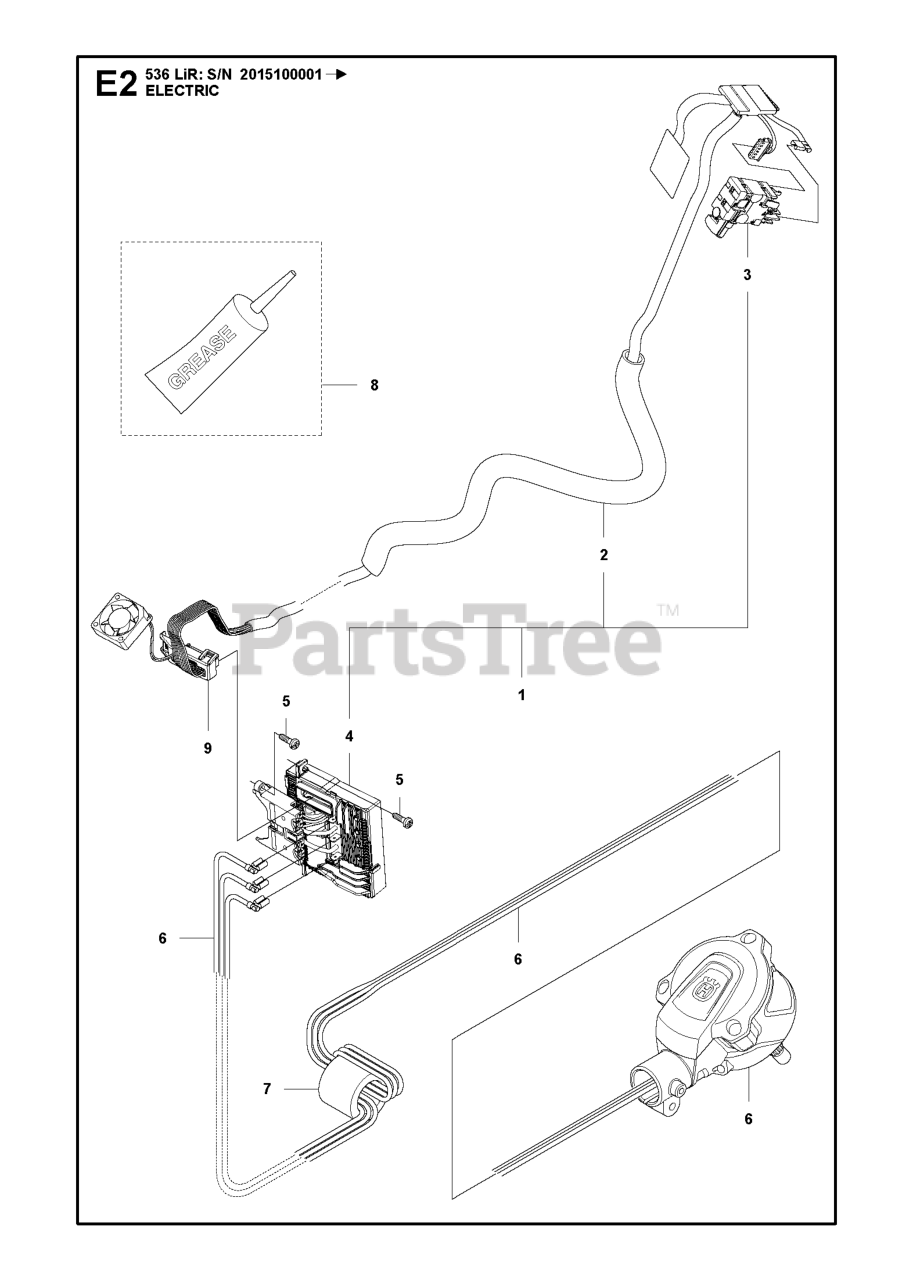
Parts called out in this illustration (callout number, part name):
3	TRIGGER SWITCH
4	CONTROL UNIT
7	GREASE TUBE Q8 RUYSDAEL WR2
8	FERRITE CORE
